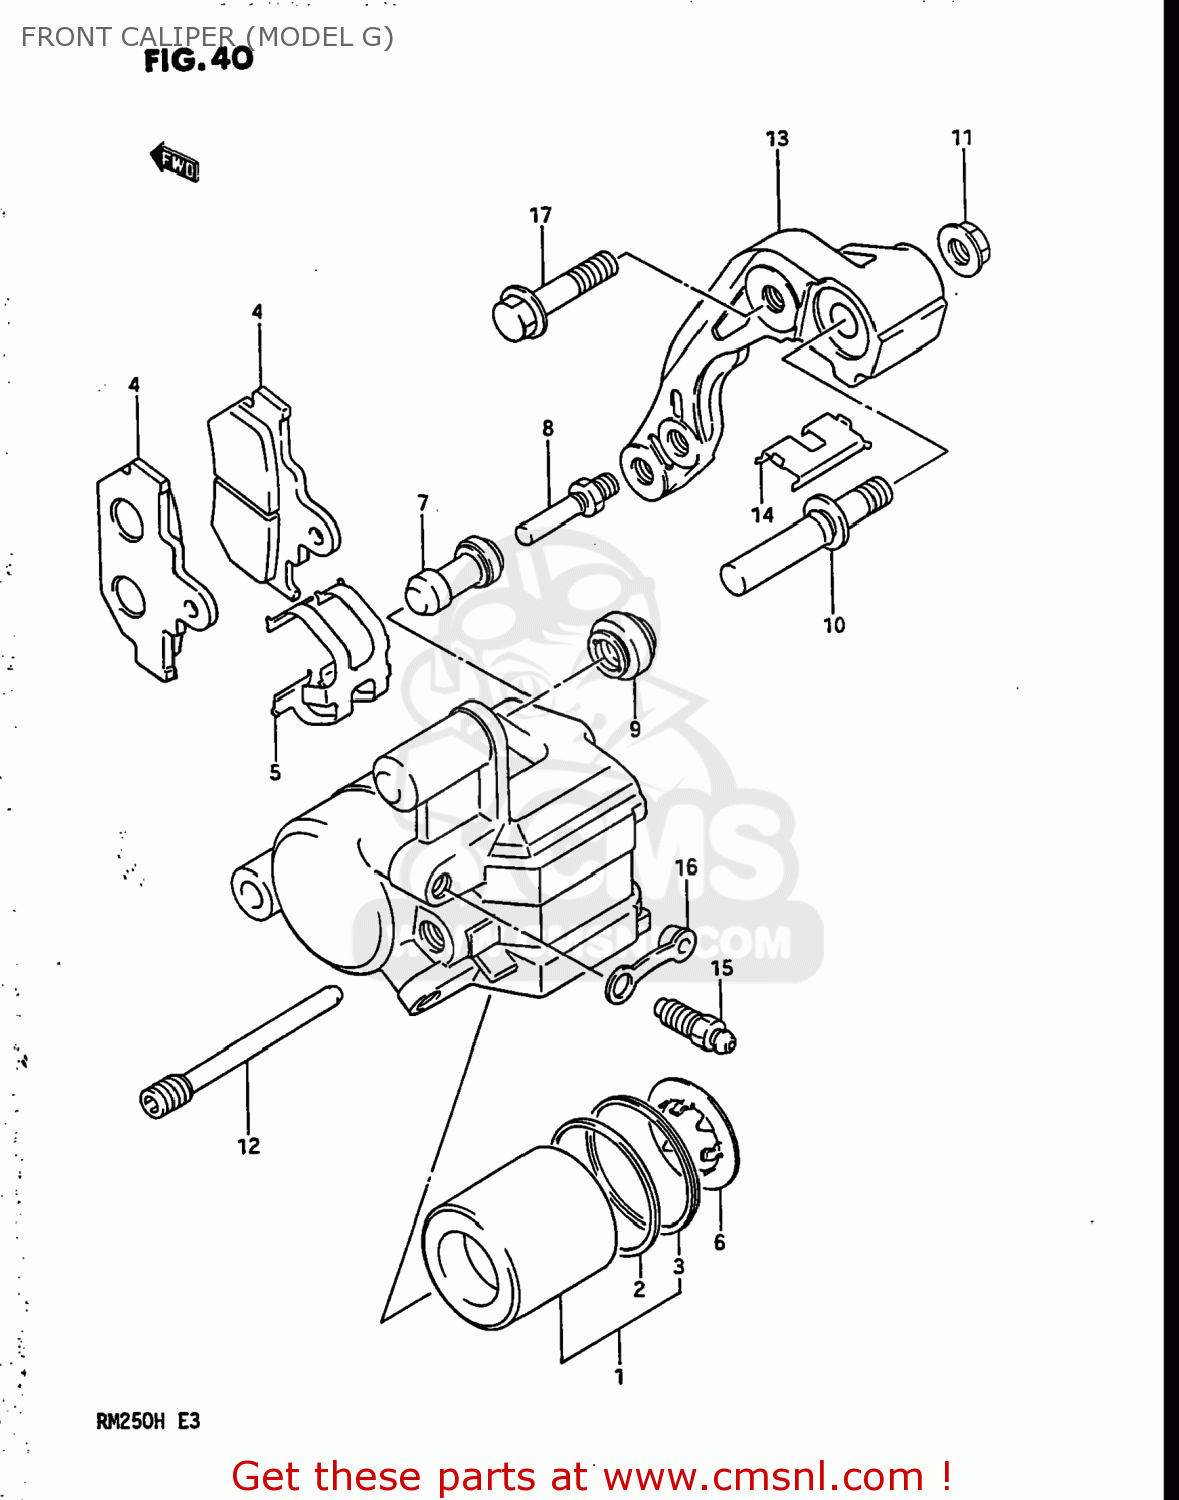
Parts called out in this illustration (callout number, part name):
1	PISTON SET,CALIPERS
2	SEAL,PISTON
3	DUST SEAL,PISTON
4	PAD
5	SPRING
6	SHIM
7	BOOT
8	PIN,BOLT
9	BOOT
10	PIN,SLIDE
11	NUT,SLIDE PIN
12	PIN,HANGER
13	BRACKET
14	RETAINER
15	BLEEDER
16	CAP,BLEEDER
17	BOLT
